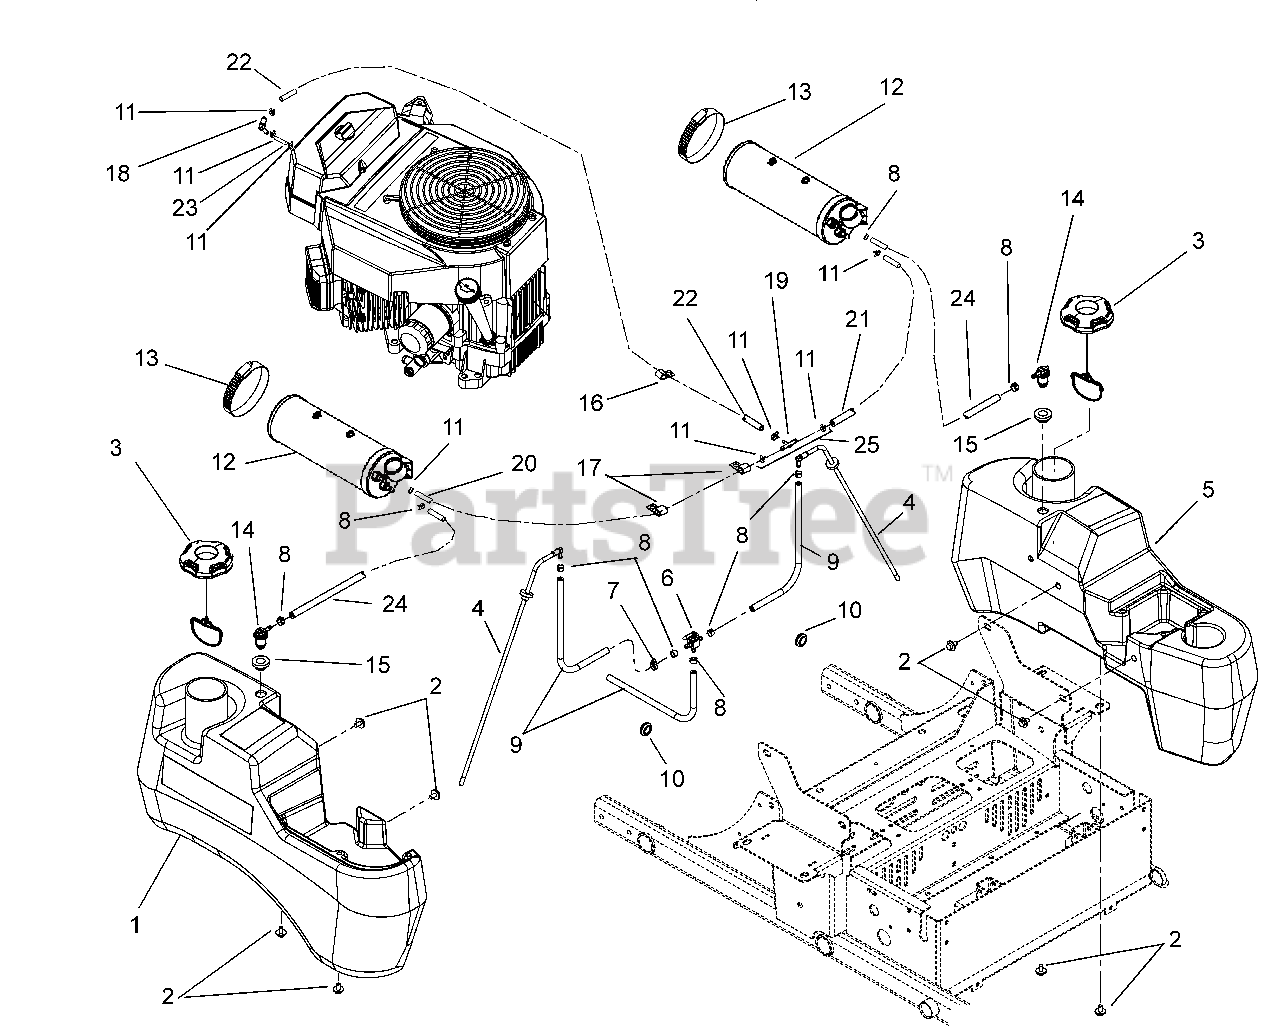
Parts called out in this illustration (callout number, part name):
1	Tank, Right Hand Fuel
2	Bolt, SEMS .31-18 x .62
3	Cap, Fuel, Non-Vented Autolock
4	Assembly, Large Tank Fuel Pick-Up
5	Tank, Left Hand Fuel
6	Valve, Fuel
7	Routing Clip (1/2" ID)
8	Clamp, Fuel Line .25
9	Hose, .25 Low-Perm Bulk Gas
10	Grommet, Rubber 5/8 ID/1.13 OD
11	Clamp, Hose, Spring .188
12	Canister, Carbon 9.36 Cap
13	Clamp, Worm Hose 2.3/3/2 SS #44
14	Valve, Combination
15	Grommet, Remote Vent Nitrile
17	Routing Clip, .50 ID
18	Hose, Elbow 90° .188
19	Assembly, Vapor Line
20	Hose, .188 Low-Perm Bulk Gas
21	Hose, .188 Low-Perm Bulk Gas
22	Hose, .188 Low-Perm Bulk Gas
23	Hose, .188 Low-Perm Bulk Gas
24	Hose, .25 Low-Perm Bulk Gas
25	Vapor Line Assembly (CARB) (Includes items 11,18, 20, 21, 22, 23)
